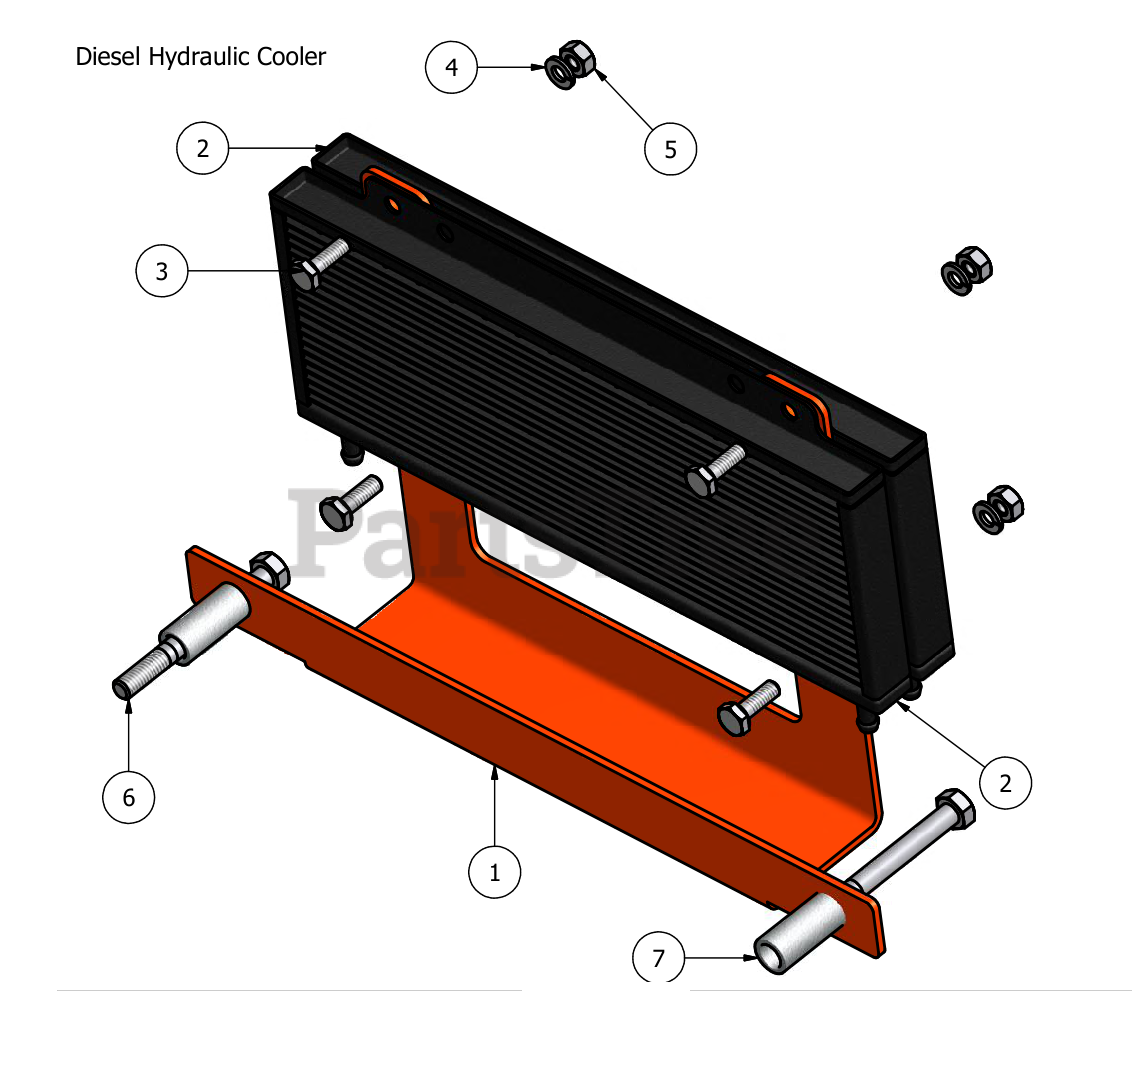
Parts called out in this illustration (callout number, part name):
1	Cooler Holder
2	Hydraulic Cooler
3	1/4" x 3/4" Hex Bolt
4	1/4" Lock Washer
5	1/4" Hex Nut
6	5/16" x 6" Bolt (28hp)
6	5/16" x 3" Bolt (35hp)
7	Cooler Holder Spacer (35hp)
7	Cooler Holder Spacer (28hp)
